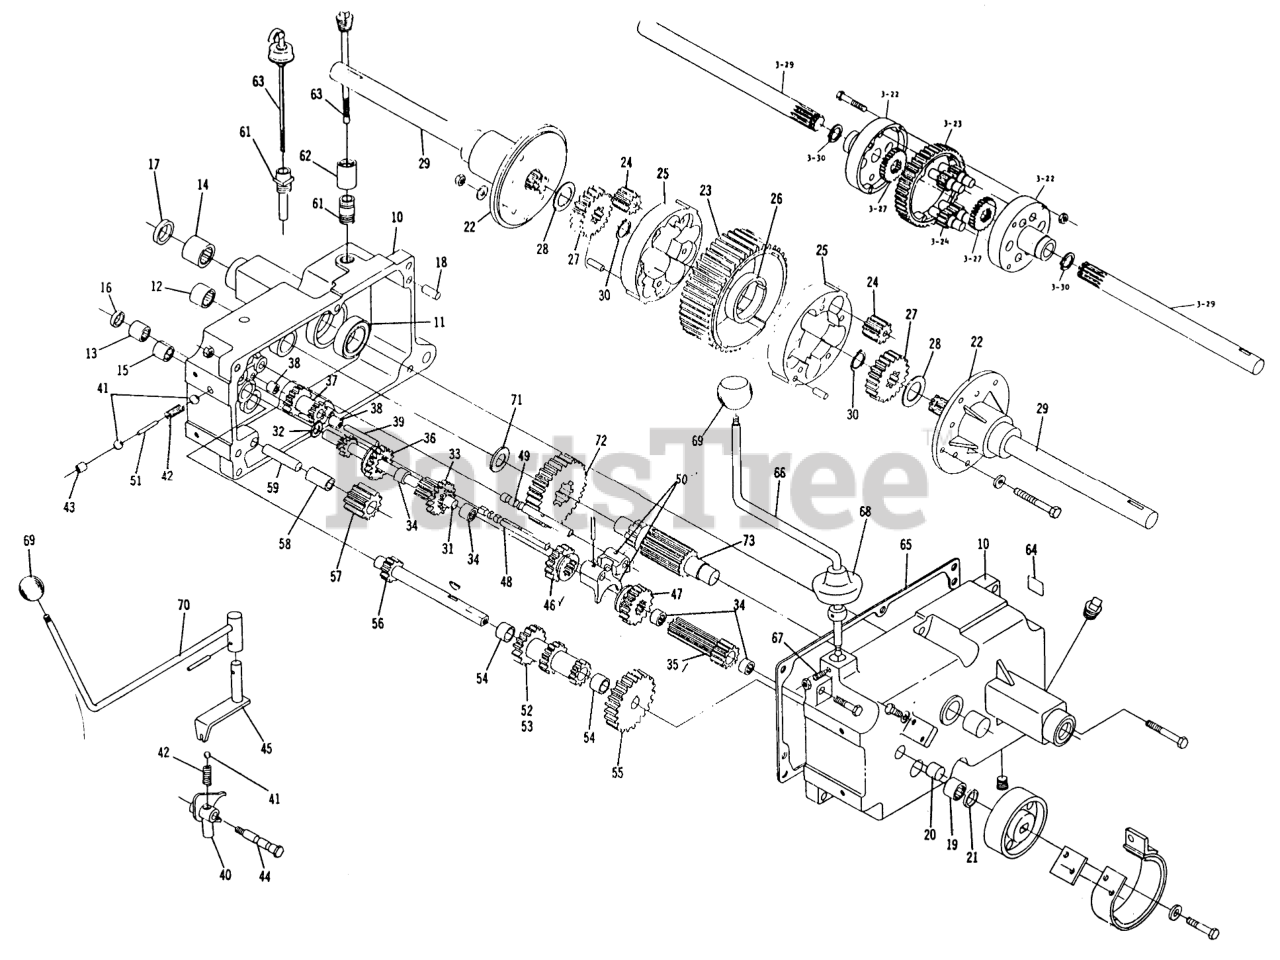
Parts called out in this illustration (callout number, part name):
3-22	End Cap R.H. (12, 14)
3-22	SVCBULLT 394
3-23	SVC BULLT 394
3-24	GEAR-PINION, 11T
3-27	SIDE GEAR
3-27	AXLE GEAR
12	BEARING-NEEDLE
13	BEARING-NEEDLE
14	BEARING-NEEDLE
15	BEARING-NEEDLE
16	SEAL-OIL
17	SEAL-OIL
17	OIL SEAL
18	PIN-DOWEL
19	BEARING-NEEDLE
21	SEAL-OIL
25	BULLT 252
31	SHAFT-INPUT
32	WASHER-THRUST
33	GEAR
34	BEARING-NEEDLE
35	GEAR
36	GEAR-SLIDING
38	BEARING-NEEDLE
39	GEAR-SHAFT REDUCTION
41	BALL-DETENT
43	CUP-PLUG
44	BOLT-DETENT
45	SHIFT ASM
46	GEAR-HI AND 2ND
47	GEAR-LOW AND REVERSE
48	RAIL-SHIFT
49	RAIL-REAR SHIFT
50	FORK-SHIFT
51	PIN-SHIFT
52	GEAR-CLUSTER
54	BUSHING-BRONZE
55	GEAR-CLUSTER SHAFT
57	GEAR/BUSHING ASM-REVERSE IDLER
58	BUSHING
59	PIN-DIFFERENTIAL
65	GASKET-TRANSMISSION
67	SETSCREW
68	COVER-DUST
69	SHIFT KNOB
71	WASHER-THRUST
73	PINION SHAFT
